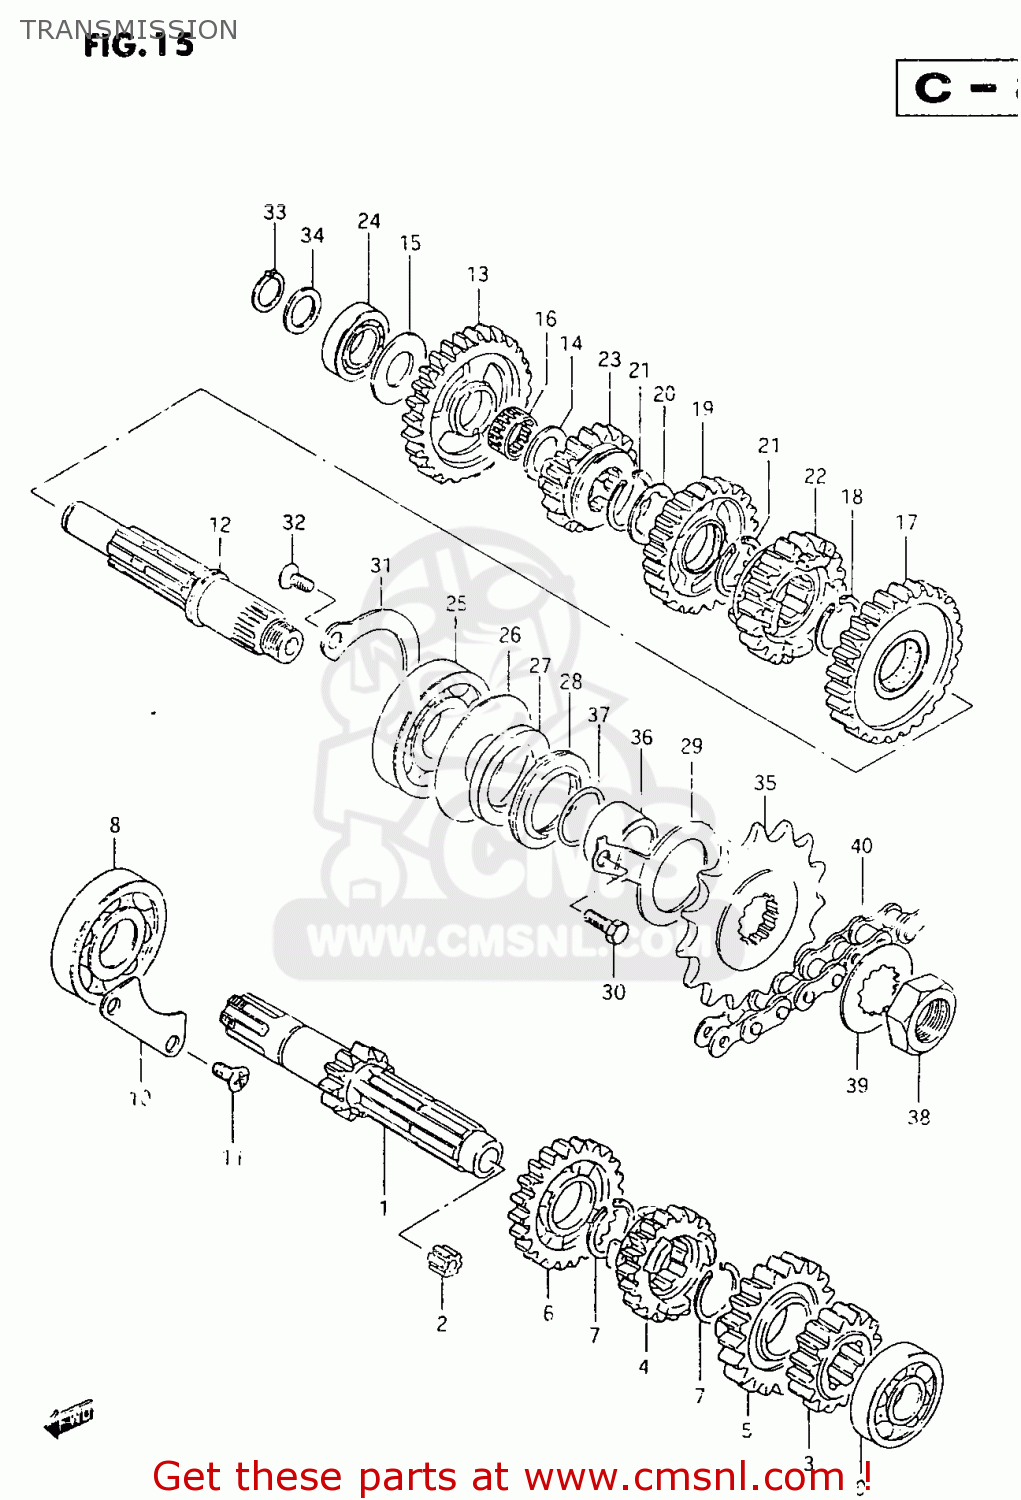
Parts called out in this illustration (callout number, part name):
1	SHAFT,COUNTER
2	BUSH
3	GEAR,2ND DRIVE(NT:16)
4	GEAR,3RD DRIVE(NT:19)
5	GEAR,FOURTH DRIVE
6	GEAR,FIFTH DRIVE
7	CIRCLIP
8	BEARING(22X56X16)
9	BEARING
10	RETAINER,CNTR SHAFT BEARING
11	SCREW
12	SHAFT,DRIVE
13	GEAR,1ST DRIVEN(NT:29)
14	SHIM(17X28X1)
15	WASHER
16	BEARING(17X21X9.8)
17	GEAR,2ND DRIVEN(NT:27)
18	CIRCLIP
19	GEAR,THIRD DRIVEN
20	WASHER,LOCK
21	CIRCLIP
22	GEAR,FOURTH DRIVEN
23	GEAR,FIFTH DRIVEN
24	BEARING(17X36X12)
25	BEARING(22X56X16)
26	WASHER(35X55X1)
27	OIL SEAL (30X43X5)
28	OIL SEAL (30X43X7)
29	RETAINER,DRIVE SHAFT OIL SEAL
30	BOLT
31	RETAINER,DRIVE SHAFT BEARING
32	SCREW
33	CIRCLIP,17MM
34	SHIM(17X24X1)
35	SPROCKET,ENGINE(NT:15)
36	SPACER
37	O RING(D:2.5,ID:21)
38	NUT
39	WASHER,LOCK
40	CHAIN(DID520VC5,100LE)
